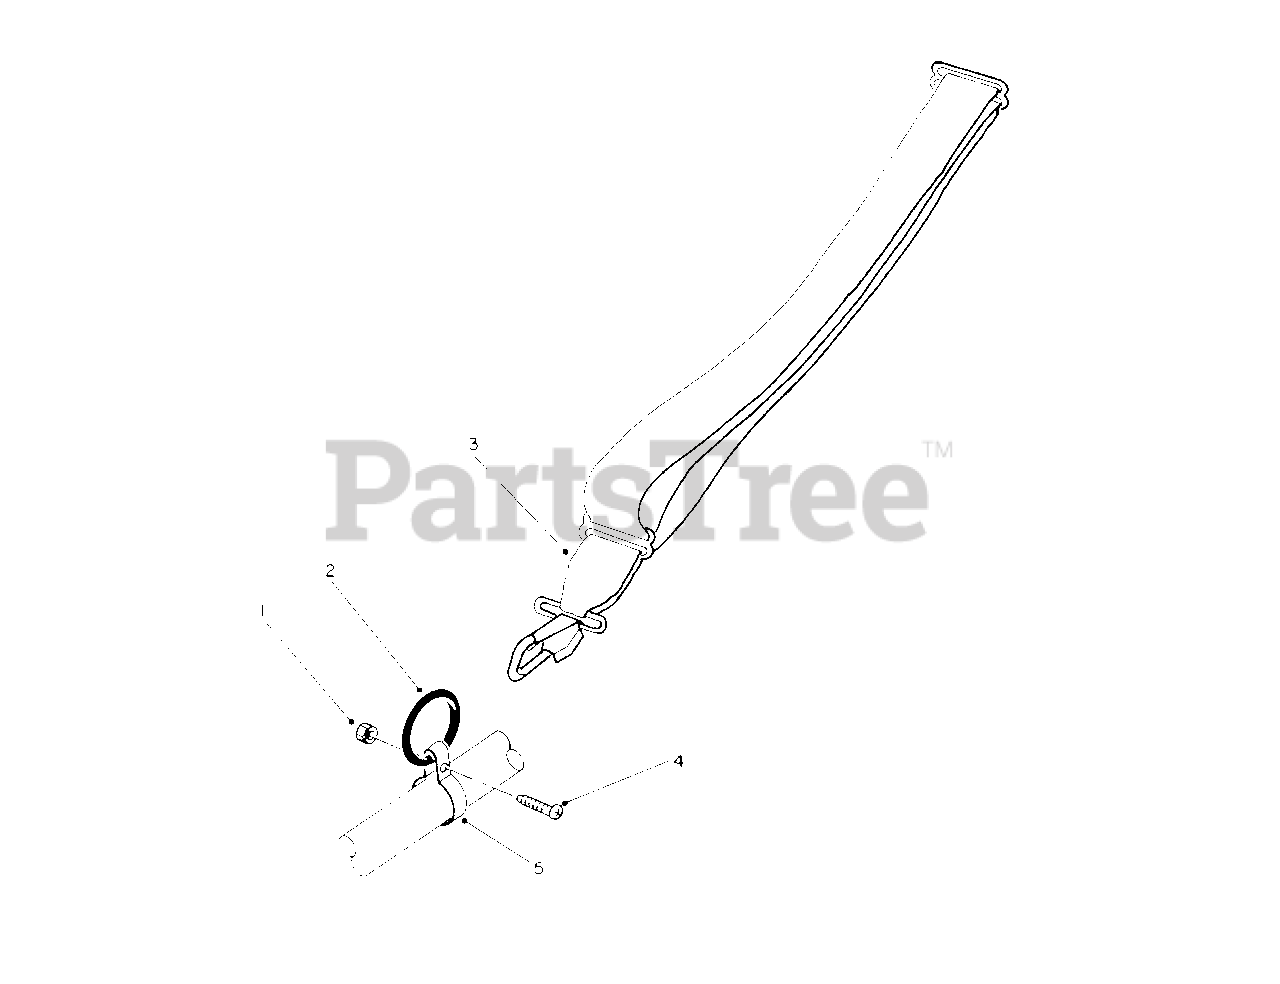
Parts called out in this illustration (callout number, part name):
1	Nut
2	Ring
3	Standard Harness
4	Clamp & Ring Kit (Incl. Ref. #1, 2, 4, & 5)
4	Screw
5	Clamp
